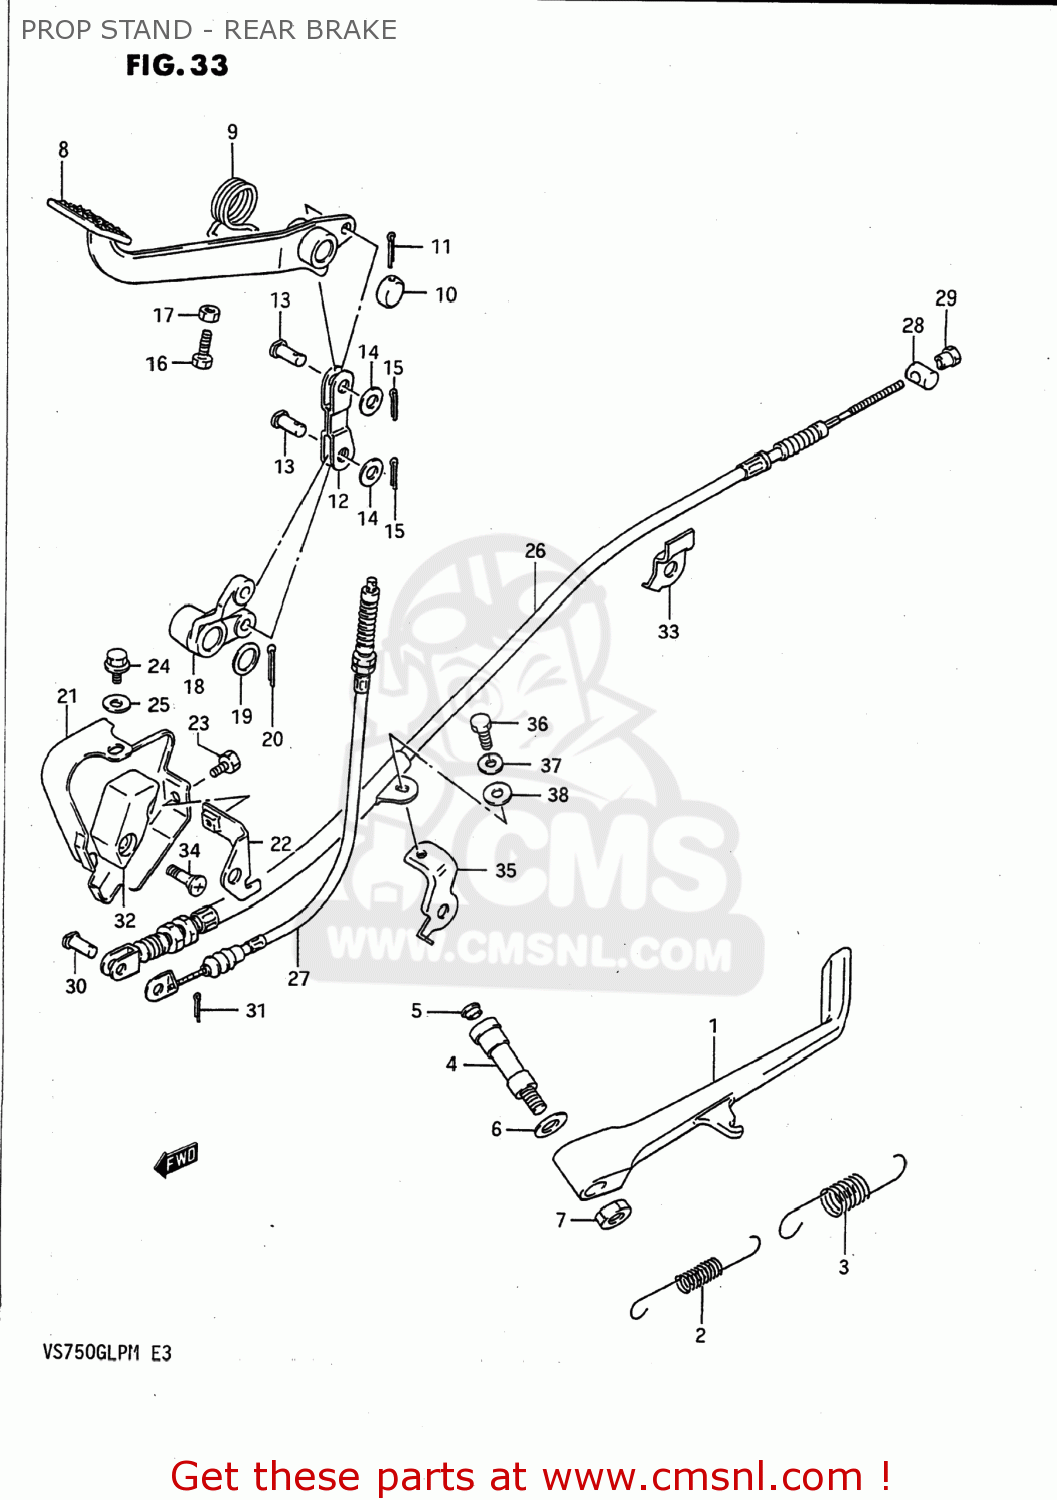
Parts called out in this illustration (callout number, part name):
1	STAND,PROP
2	SPRING
3	SPRING
4	BOLT,PROP STAND
5	CAP
6	THRUST WASHER
7	NUT
8	PEDAL,BRAKE
9	SPRING
10	CAP,BRAKE PEDAL
11	COTTER PIN
12	LINK COMP,BRAKE ROD NO
13	PIN
14	WASHER
15	PIN
16	BOLT
17	NUT 6MM
18	ARM,BRAKE PEDAL LINK
19	WASHER (16.5X42X2.6)
20	COTTER PIN
21	COVER,BRAKE
22	BRACKET COMP,BRAKE COVER
23	SCREW(6X10)
24	BOLT
25	WASHER(6.5X15X1.0)
26	CABLE ASSEMBLY,REAR BRAKE
27	CABLE,STOP LAMP SWITCH
28	PIN
29	NUT (6MM)
30	PIN(L:17.5)
31	PIN
32	GUIDE,RR BRAKE CABLE
33	CLAMP,RR BRAKE CABLE
34	SCREW
35	BRACKET,RR BRAKE CABLE
36	BOLT
37	WASHER,LOCK
38	WASHER 6MM
